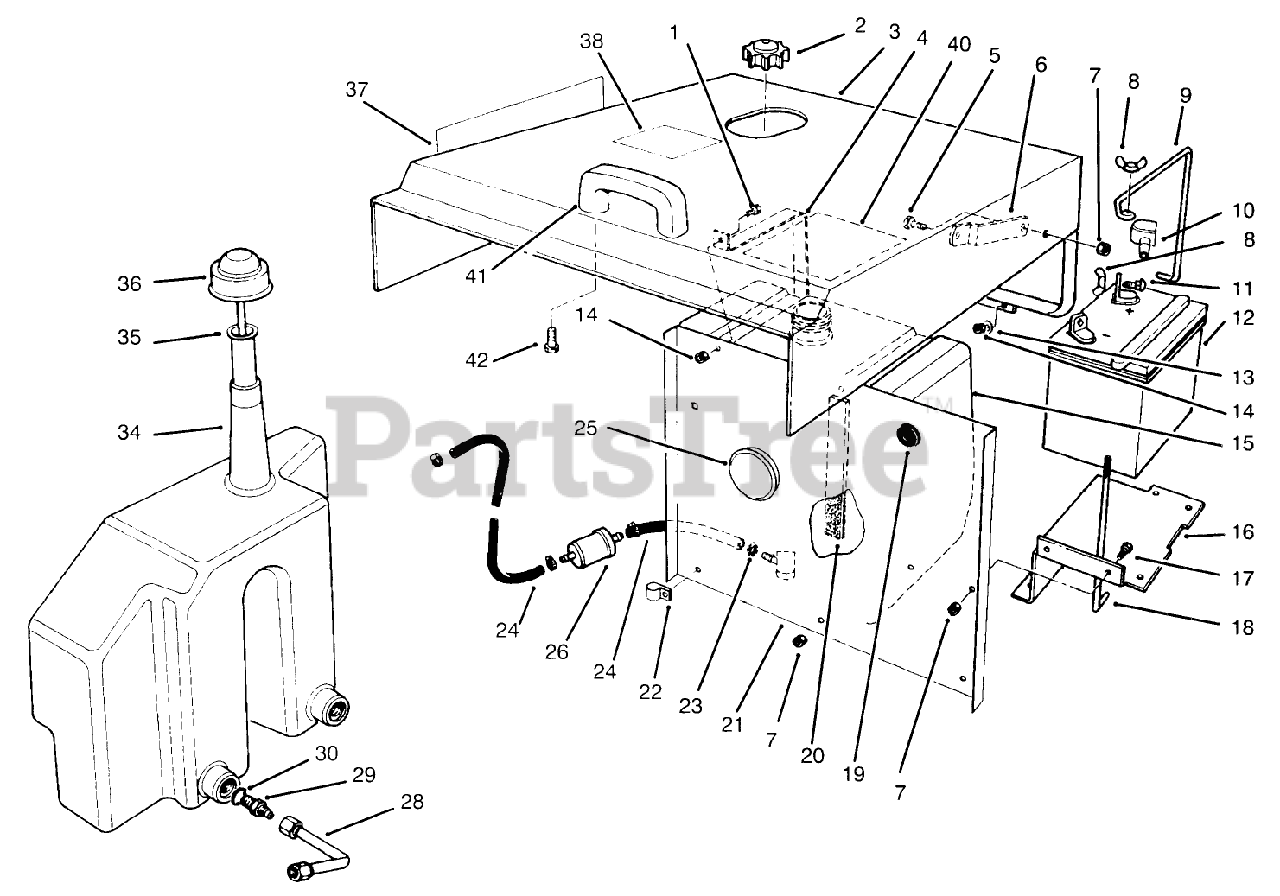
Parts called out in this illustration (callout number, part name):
1	SCREW-HH
2	GAS CAP ASM
3	HOOD-118 - SERVICE
4	Strap-Fuel Tank
5	SCREW-HH
6	UPPER HOOD STOP
7	NUT-LOCK, NI
8	NUT-WING
9	BATTERY CLAMP
10	BOOT-TERMINAL, RED
11	BOLT-CARR
12	Battery
13	WASHER-FLAT
14	NUT-LOCK, NI
15	TANK-FUEL
16	Support-Battery
17	SCREW-HH
18	ROD-SUPPORT, BATTERY
19	GROMMET
20	TANK SPONGE
21	Shield-Heat
23	CLAMP-WORM
24	GAS HOSE
25	PLUG BUTTON CAP
26	FUEL FILTER
28	TUBE ASM
29	Fitting-Hydraulic Straight (Incl. Ref. #30)
30	O-RING
34	OIL RESERVOIR
35	SCREEN-FILLER
36	CAP WA
37	DECAL - GM 120
38	DECAL - CAUTION FUEL
40	DECAL - SERVICE PL120
41	HANDLE-DOOR
42	SCREW-HWH
